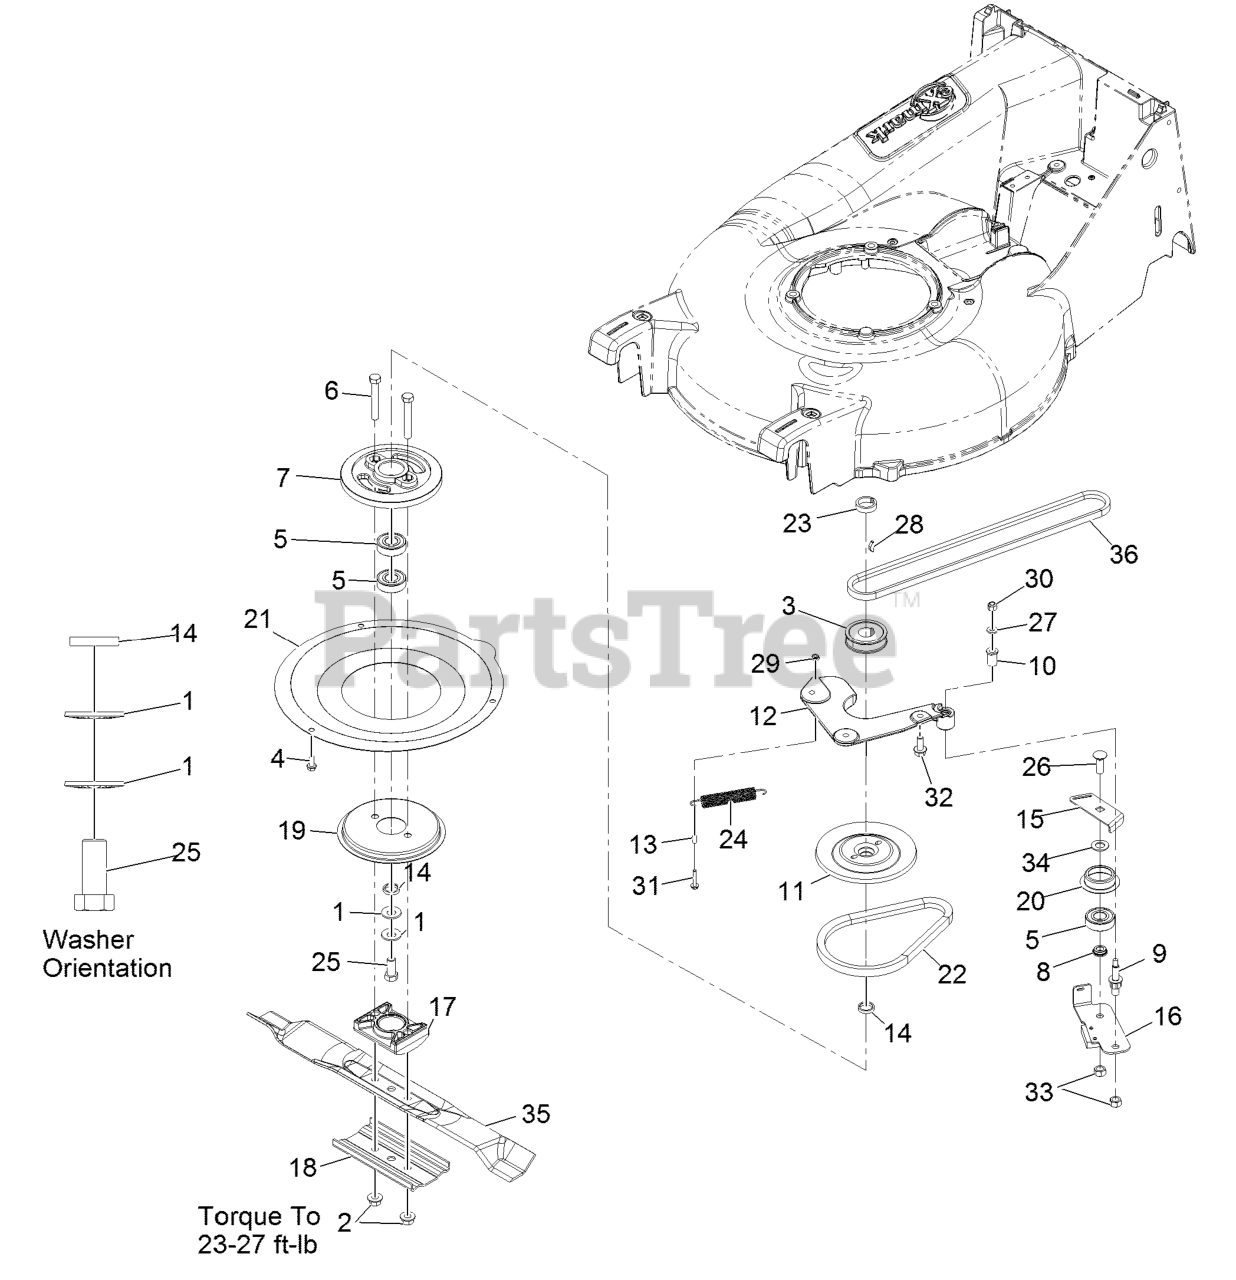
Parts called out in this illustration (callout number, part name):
1	WASHER-SPRING
2	Nut-Hex 3/8-24 Lock
3	PULLEY-DRIVER
4	SCREW-HWH
6	SCREW-HH
8	SPACER-BEARING
9	BOLT-SHOULDER
10	BUSHING
11	Pulley- Driver, Upper
12	PLATE-MOUNTING, BBC
13	SPACER-BBC
14	SPACER-PLATE, BBC
15	PLATE-GUIDE
17	SUPPORT-BLADE
18	SUPPORT-BLADE
19	DISC
20	RETAINER-BELT
21	COVER-BBC
22	BELT
23	SPACER-PULLEY
24	SPRING-EXTENSION
25	SCREW-HH
26	SCREW-CARR
27	WASHER-FLAT
28	KEY-WOODRUFF
29	NUT-LOCK, NI
30	NUT-LOCK, NI
31	SCREW-TAP
32	SCREW-HHF
33	LOCKNUT
34	SPACER
36	BELT,3L P21 DRIVE
